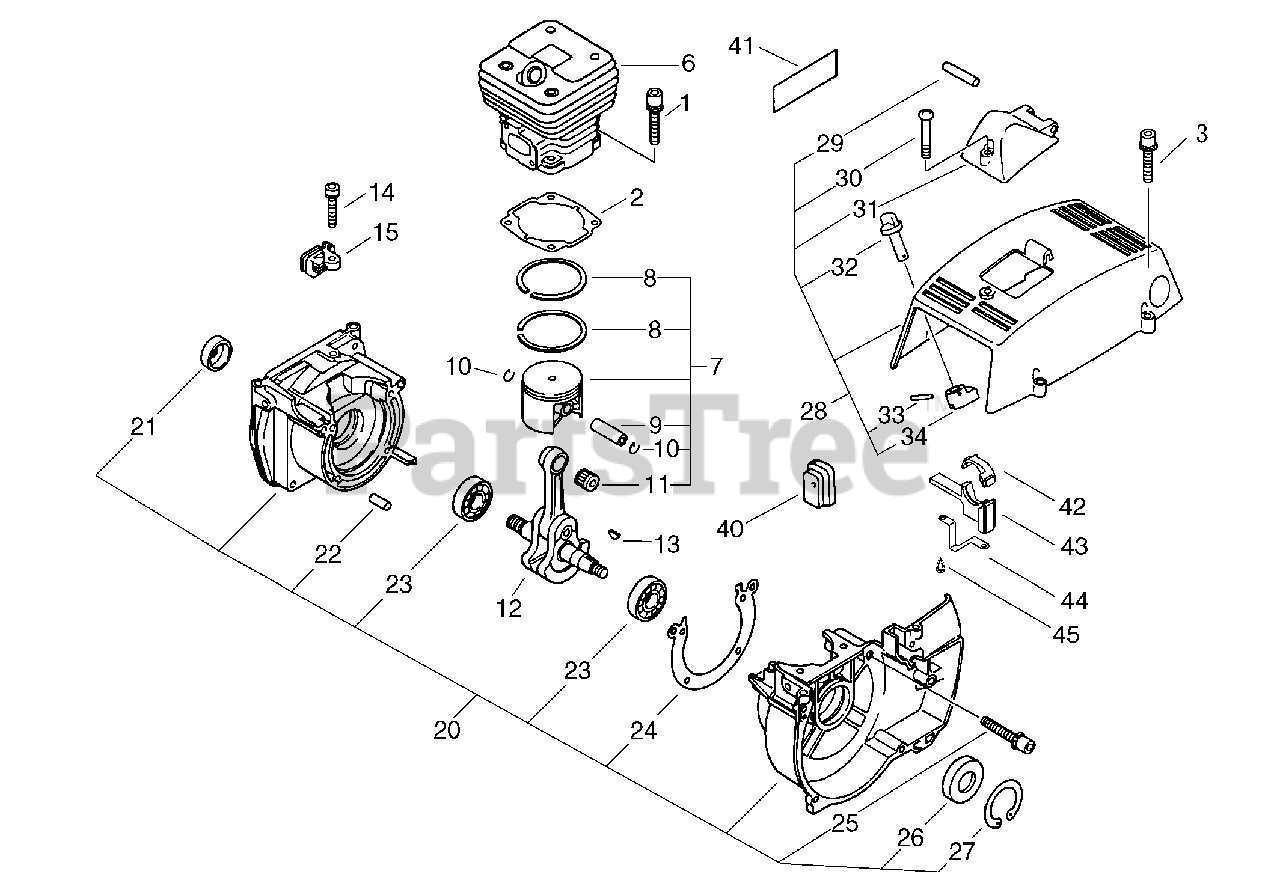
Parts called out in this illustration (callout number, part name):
1	BOLT 5×22
2	GASKET, CYLINDER
3	BOLT 5×22
6	CYLINDER
7	PISTON KIT
8	RING, PISTON
9	PIN, PISTON
10	RING, SNAP 8
11	BEARING, NEEDLE 10
12	CRANKSHAFT
13	KEY, WOODRUFF 3×14
14	BOLT 5×16
15	BRACKET, THROTTLE
20	CRANKCASE KIT
21	SEAL, OIL
22	PIN, LOCATING 4×8
23	BEARING, BALL 6203 C3
24	GASKET, CRANKCASE
25	BOLT M5×35
26	SEAL, OIL 18
27	RING, SNAP 35
28	COVER, CYLINDER
31	COVER, SPARK PLUG CAP
32	ROD, CHOKE
33	PIN, SPRING - 2×10
34	END, LEVER
41	LABEL, ECHO
44	PLATE, ANGLE
45	SCREW 4×16
